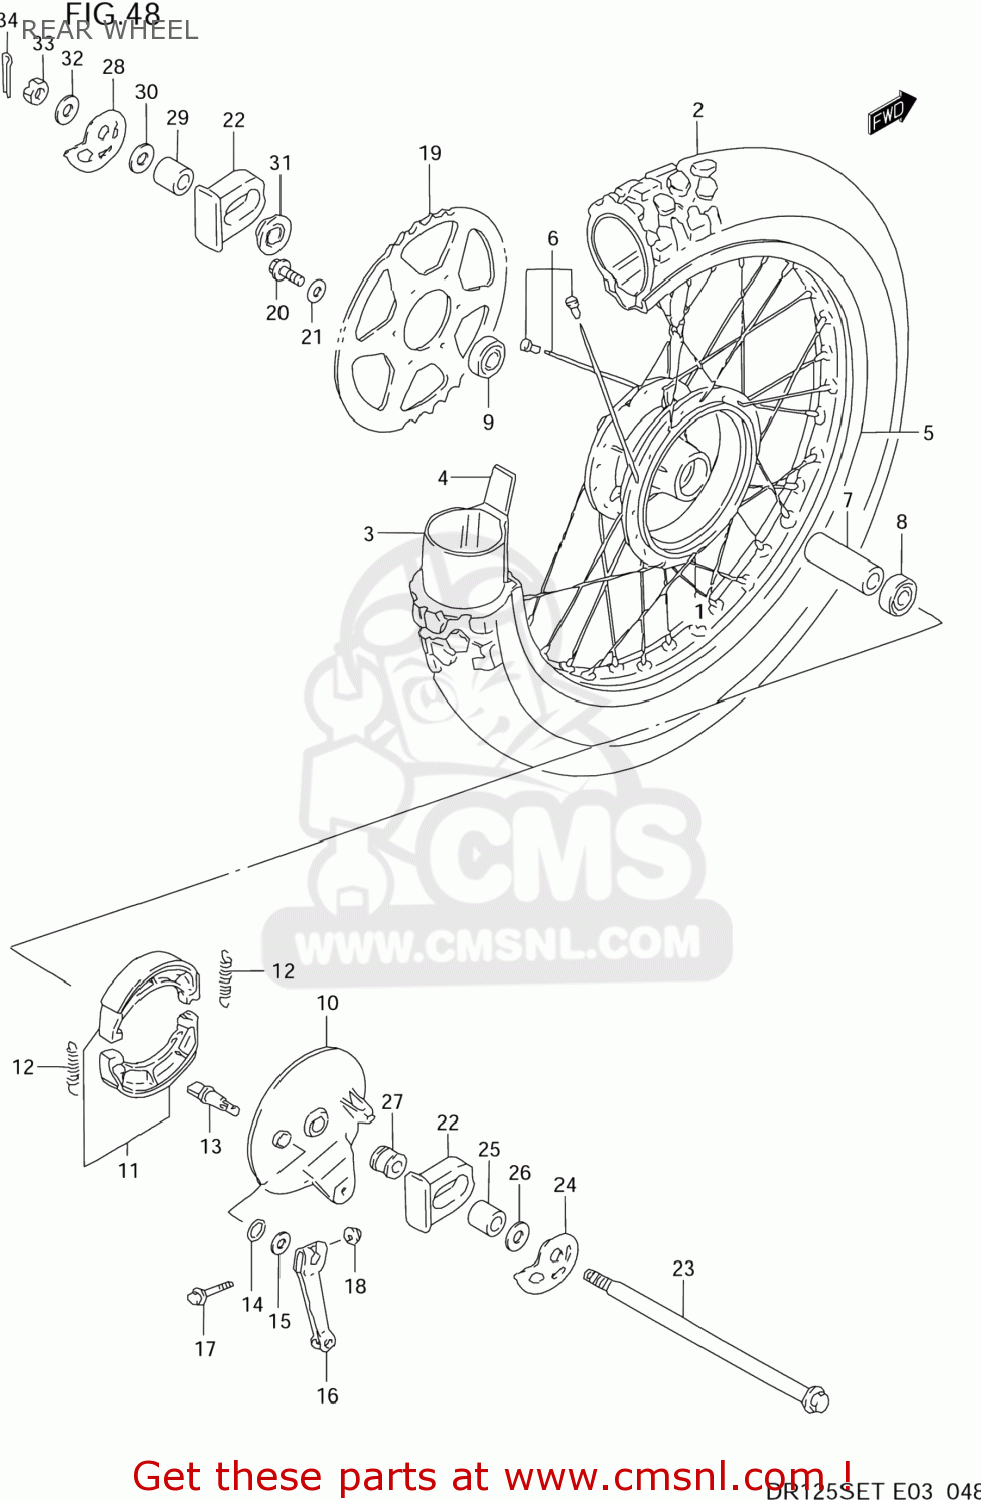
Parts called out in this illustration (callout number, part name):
1	HUB,RR WHEEL
2	TIRE,RR(90/90-18 51P)
3	TUBE ASSY,INNER
4	PROTECTOR,INNER TUBE
5	RIM,RR WHEEL(18X1.85 FE)
6	SPOKE SET,RR WHEEL
7	SPACER(15.3X21.7X107.5)
8	BEARING
9	BEARING
10	PANEL,RR BRAKE ANCHOR
11	SHOE SET,BRAKE (NAS)
12	SPRING(L:34)
13	CAM,BRAKE
14	O-RING (D:2.4 ID:13.8)
15	WASHER (14.5X22X1.6)
16	LEVER,RR BRAKE CAM
17	BOLT
18	NUT
19	SPROCKET,REAR
20	BOLT(8X30)
21	WASHER
22	CAP,RR SWINGING ARM
23	AXLE,RR
24	ADJUSTER,CHAIN,R
25	SPACER,CHAIN ADJUSTER
26	WASHER(15.5X26X2.3)
27	SPACER,RR AXLE,R
28	ADJUSTER,CHAIN,L
29	SPACER,CHAIN ADJUSTER
30	WASHER(15.5X26X2.3)
31	SPACER,RR AXLE,L
32	WASHER
33	NUT
34	COTTER PIN
